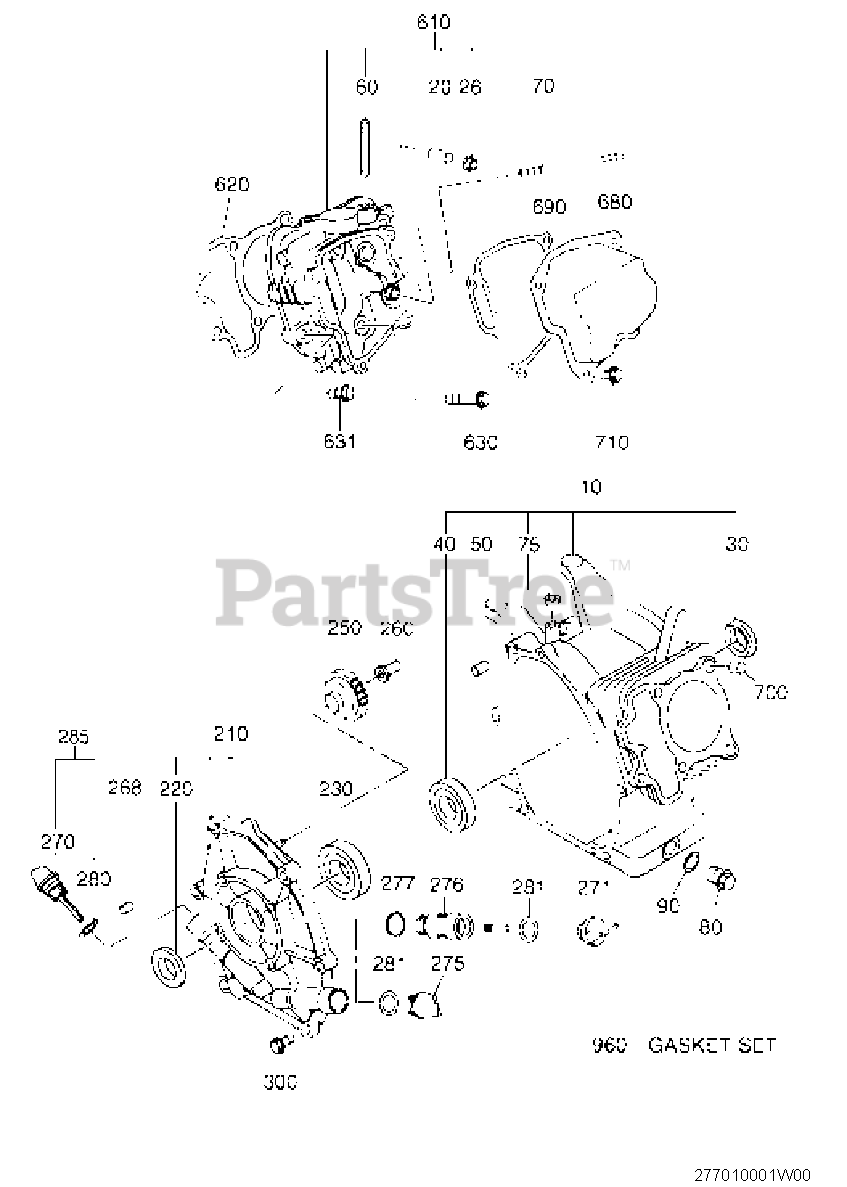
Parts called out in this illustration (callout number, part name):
75	OIL SEAL 6X10X2.5
210	MAIN BEARING COVER C
250	GOVERNOR GEAR CP
260	GOVERNOR SLEEVE
610	CYLINDER HEAD CP
680	ROCKER COVER CP
690	GASKET(ROCKER COVER)
